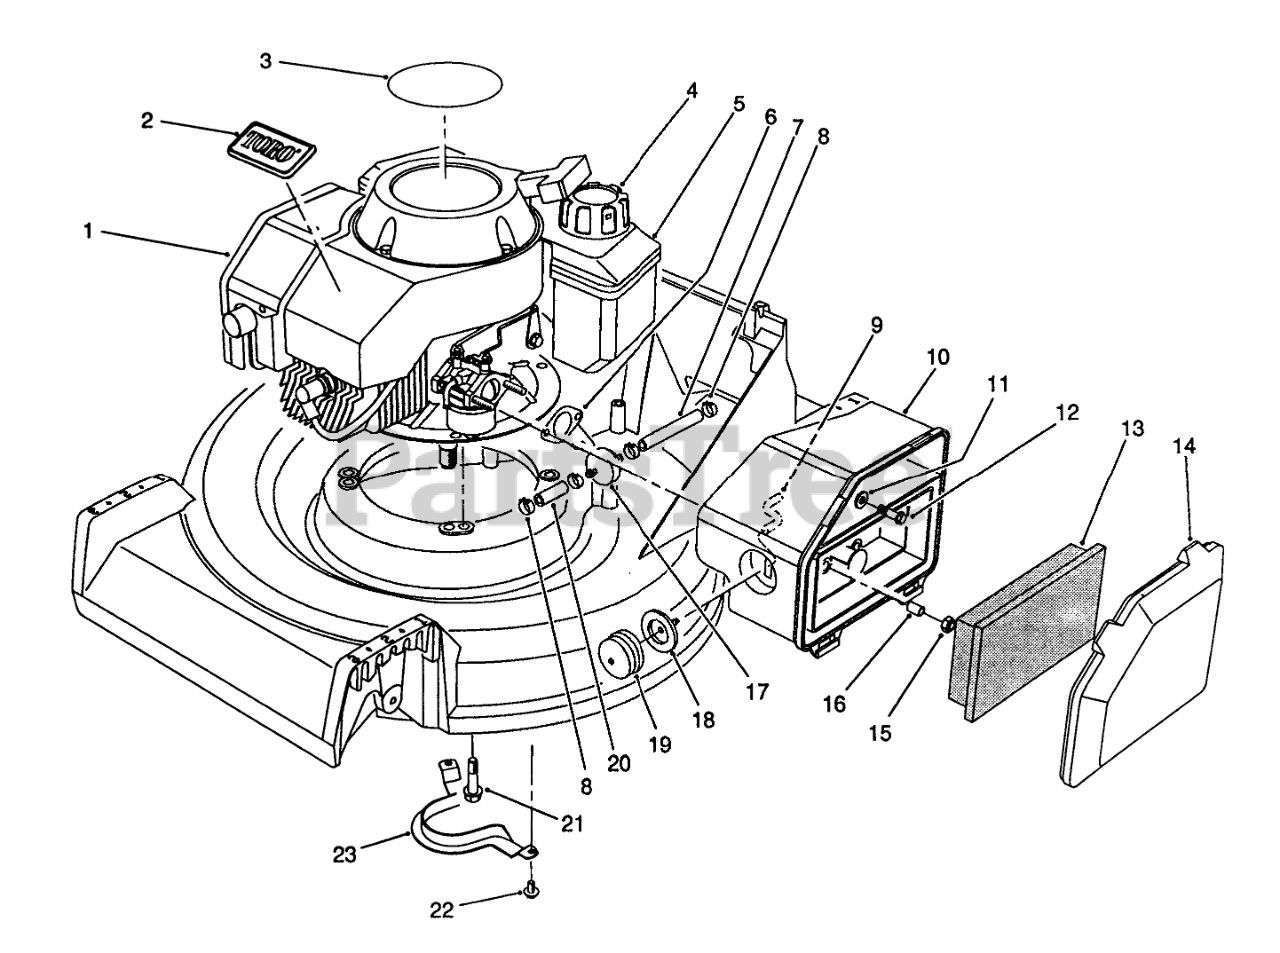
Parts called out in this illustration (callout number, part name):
1	Engine
2	TORO LOGO PLT
3	DECAL - 2 CYC RECOIL
4	GAS CAP ASM
5	FUEL TANK ASM
6	GASKET-AIR CLEANER
7	HOSE-FUEL
8	CLAMP-FUEL LINE
9	HOSE-PRIMER
10	BODY-AIR CLEANER
11	WASHER-FLAT
12	SCREW-HH
13	ELEMENT-AIR CLEANER
14	COVER-AIR CLEANER
16	SPACER
17	FILTER-FUEL
18	BODY-PRIMER
19	BULB-PRIMER
20	HOSE-FUEL
21	SCREW-HHF
22	SCREW-HWHTF
23	Guide-Belt
